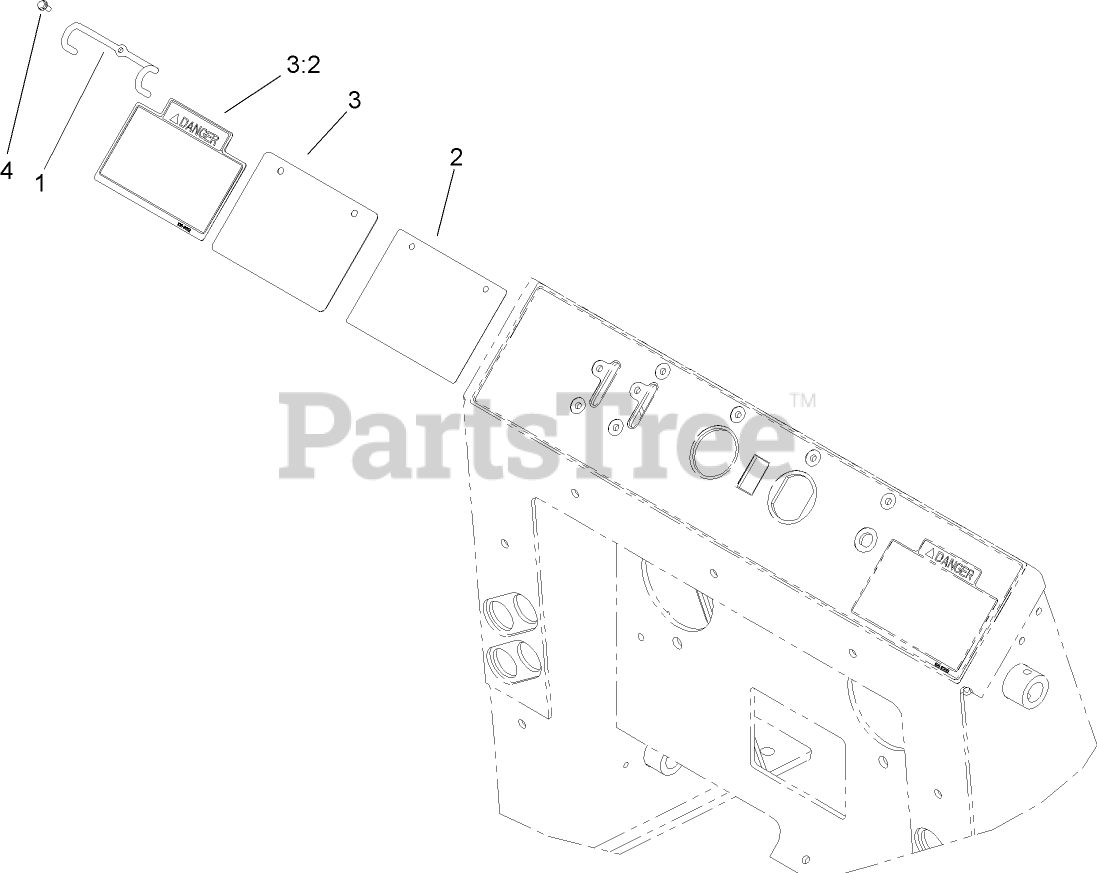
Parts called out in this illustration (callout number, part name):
1	LOOP-LOCKING
2	GUIDE-REFERENCE
3	PLATE-REFERENCE
3:2	DECAL-DANGER
4	SCREW-TAPTITE
